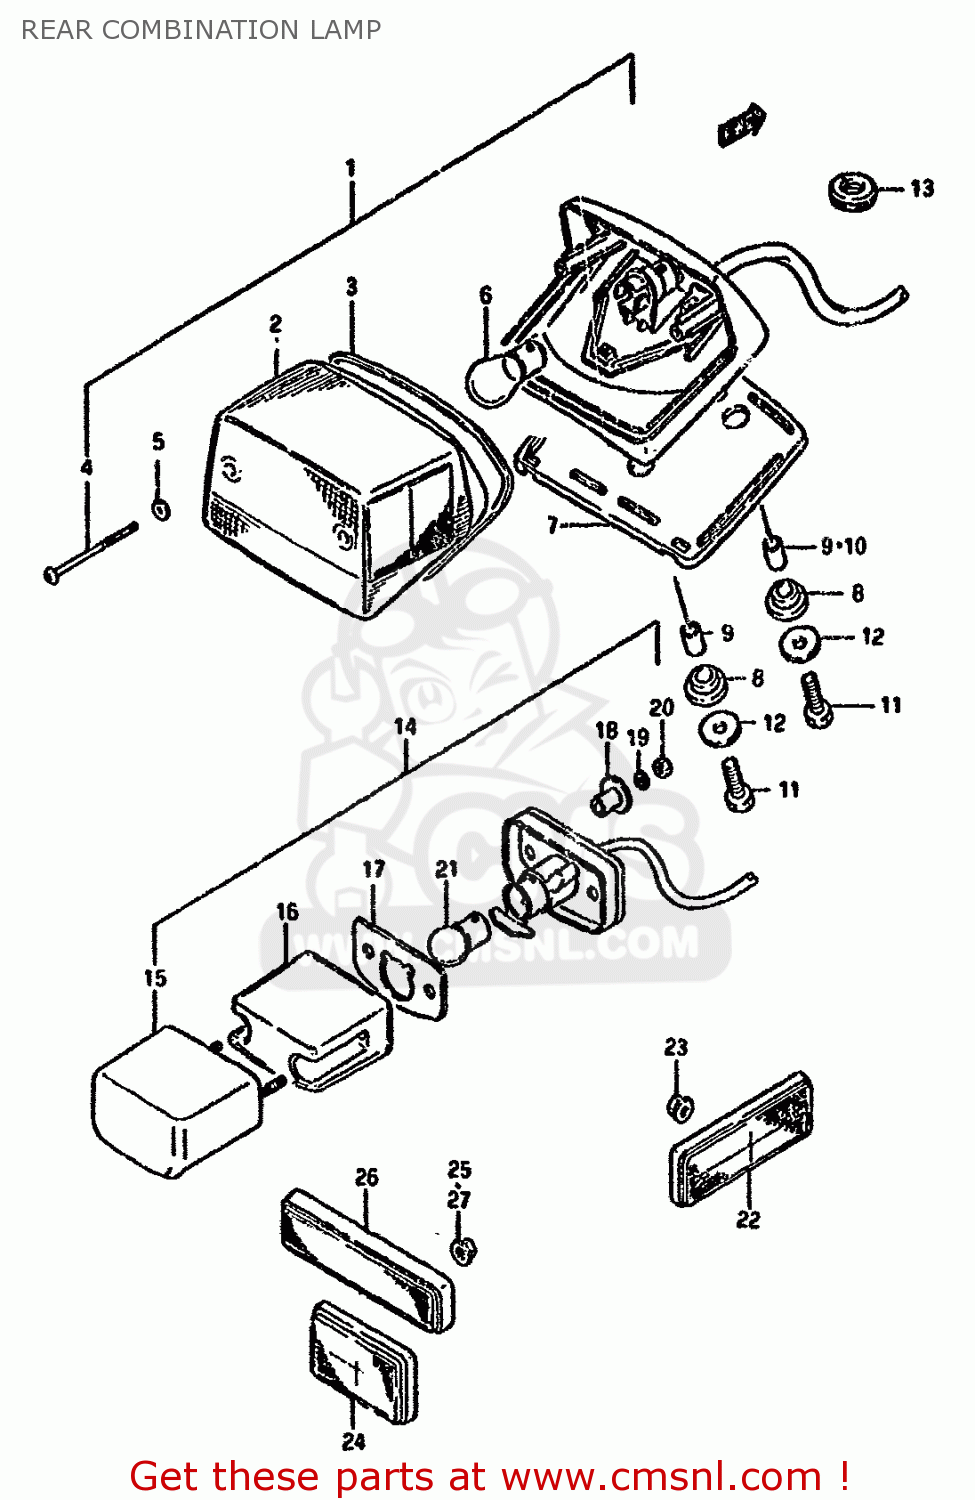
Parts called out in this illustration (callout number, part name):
1	LAMP ASSY,RR C
2	LENS
3	GASKET (NAS)
4	SCREW
5	GASKET (NAS)
6	BULB(12V21/5W)
7	CUSHION
8	CUSHION
9	SPACER
10	SPACER
11	BOLT
12	WASHER
13	GROMMET
14	LAMP ASSEMBLY,LICENSE
15	COVER,LICENSE LAMP
16	LENS
17	GASKET,LICENSE LAMP (NAS)
18	SPACER
19	WASHER,LOCK 4M
20	NUT
21	BULB
22	REFLEX REFLECTOR,FR SIDE
23	NUT
24	REFLEX REFLECTOR ASSY,RR
25	NUT
26	REFLEX REFLECTOR ASSY,RR
27	NUT
